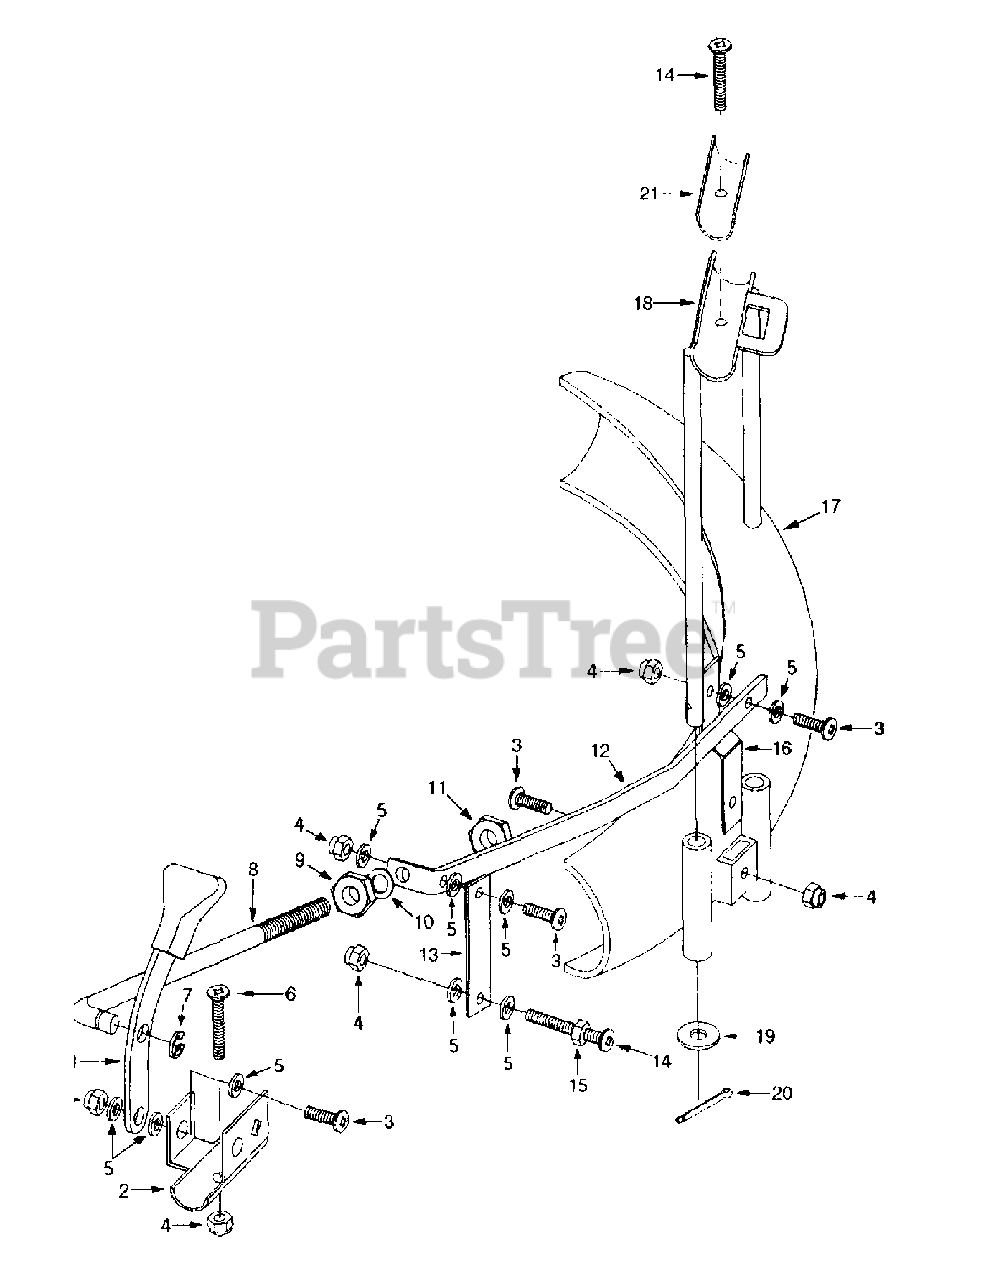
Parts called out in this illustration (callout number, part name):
1	Operating Lever and Rubber Handle
2	Bracket, Dual Lever
3	Machine Screw, 1/4-20 x 7/8 Pan Hd.
4	Hex Nut, 1/4-20 Nylock
5	Flat Washer, 1/4 Nylon
6	Mach. Screw, 1/4-20 x 1-1/2 Pan Hd.
7	Retainer, "C" Clip
8	Threaded Rod, Deflector
9	Hex Nut. 5/16-18
10	Lock Washer. 5/16
11	Hex Nut, 5/16-18 Nylock
12	Deflector Arm
13	Flat Plate, Deflector
14	Machine Screw, 1/4-20 x 2 Pan Hd.
15	Hex Nut.1/4-20
16	Offset Bracket
17	Deflector Tube
18	Deflector Bracket
19	Flat Washer, 3/8
20	Cotter Pin, 1/8 x 1
21	Rubber Pad
